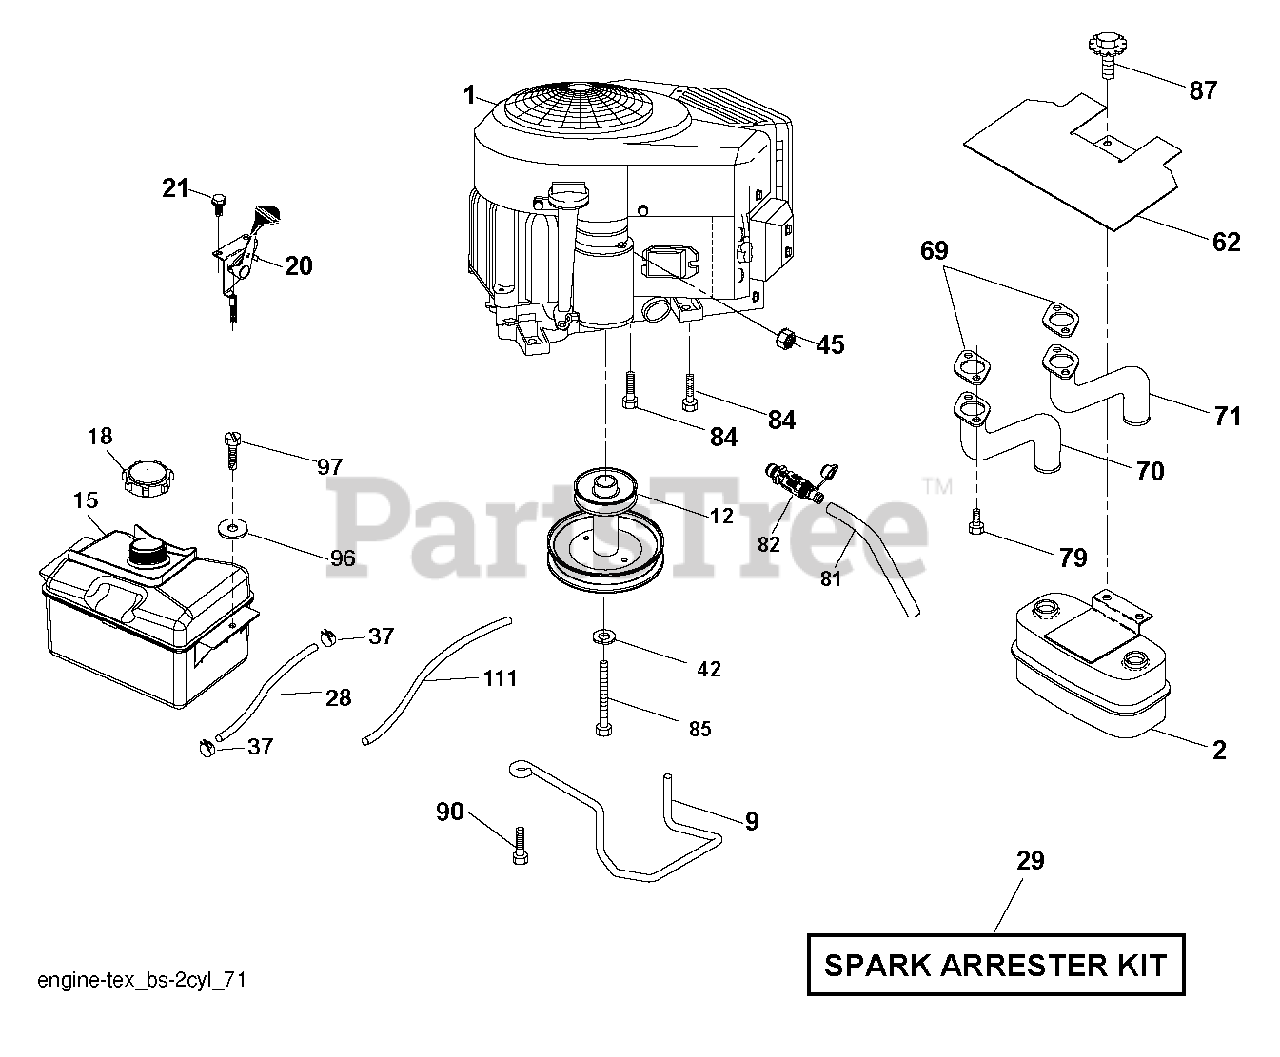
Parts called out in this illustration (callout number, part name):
2	MUFFLER.TWIN.CYL.LOW.TONE
9	KEEPER.BELT.ENGINE.3.25
12	PULLEY.ENGINE.5.0.PD
15	TANK.ASM.FRT.2.5 GAL.W/CAP.EPA
18	CAP.FUEL.2 WAY VENT
20	CONTROL.TH/CK.COBRA.B&S.TWN.
21	SCREW.#10 X 0.750.BOS (2 2)
28	LINE.FUEL.20"FRONT.EMI
29	KIT.SPARK ARRESTOR(392390 B&S)
37	HOSE CLAMP
42	LOCKWASHER
45	NUT
62	SHIELD.HEAT.MUFFLER
70	EXHAUST.TUBE.LH.BS/TWIN
71	EXHAUST.TUBE.RH.B&S.TWIN.INTEK
79	SCREW.SOCKET.HEAD.5/16-18
81	TUBE, DRAIN OIL ASM.
82	VALUE.OIL.DRAIN
84	SCREW.3/8-16
85	BOLT HEX 7/16-20X4-1/4"
87	BOLT, 5/16-18 X 1 3/4
90	SCREW 3/8-16X1
96	WASHER
97	SCREW HEXWSHR 1/4-20X3/4
111	RP PURGE LINE
